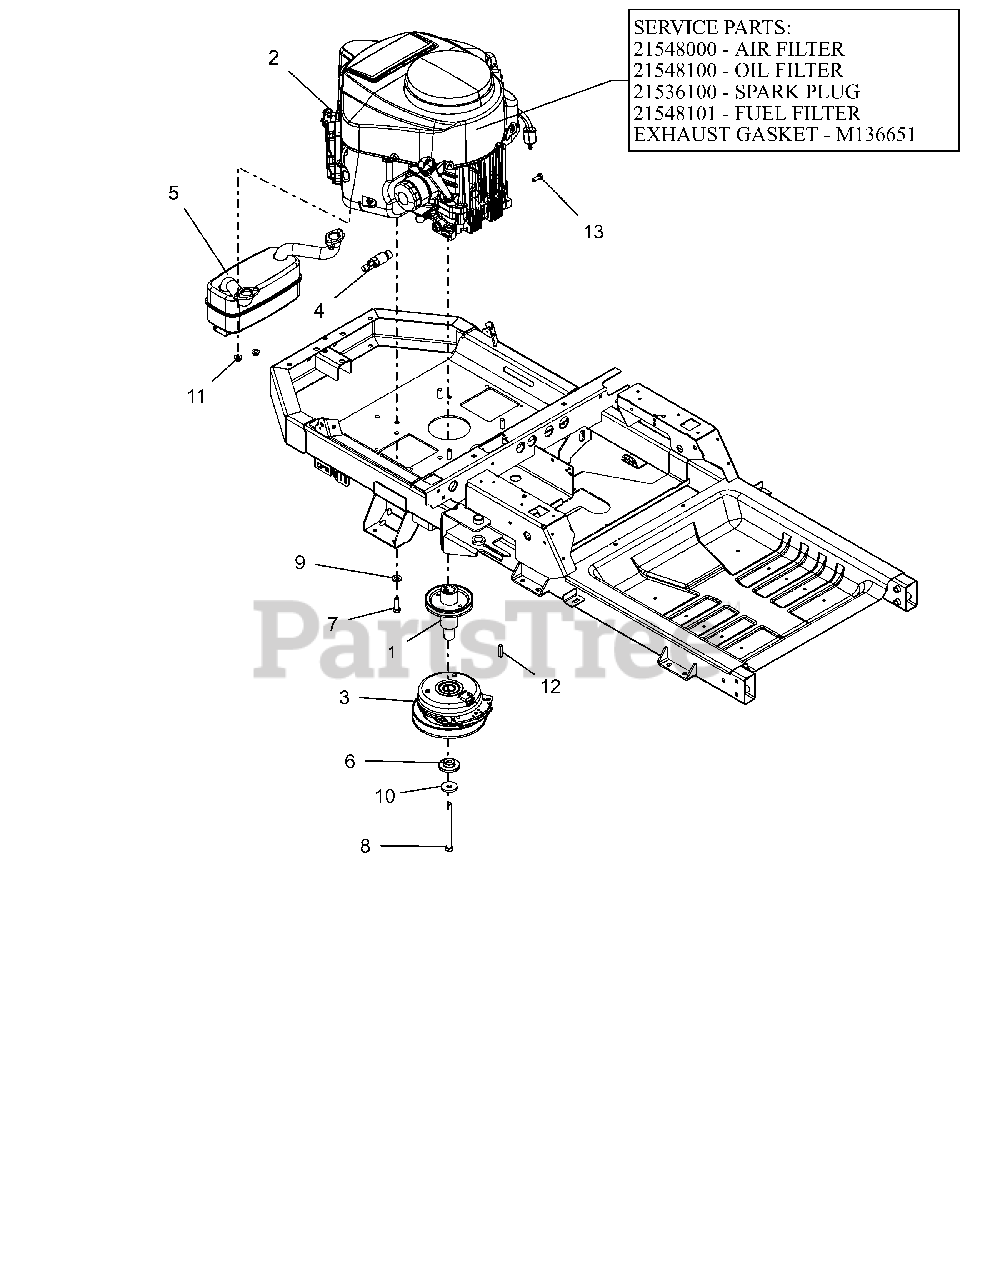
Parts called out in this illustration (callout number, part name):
1	WLDMT, DRIVE SHEAVE (LG XL)CZC
2	ENGINE, KAWASAKI FR730 24HP
2	AIR FILTER, KAWASAKI FR
2	OIL FILTER, KAWASAKI FR
2	PLUG, SPARK
2	FUEL FILTER-KAWASAKI FR
2	GASKET, MUFFLER #
3	CLUTCH,105FTLB MONOPOLE 6.83"
4	DRAIN, OIL M20X2.5
5	MUFFLER - KAWASAKI
6	BSHG-FLG .469X1.06X.574X2.0
7	BLT, HEX .38-16X1.25 G5 ZCC NT
8	BLT-HEX.438-20X5 GR8 YZ NYTORQ
9	WASHER, 3/8" SPRING DISC
10	WASHER, 7/16" SPRING DISK
11	NUT-LK-TOP-FLG M8 ZCC
12	KEY-SQ .25 X 1.25 X .25 SAE
13	BLT, HEX M8-1.25X20 G8.8 ZCC
